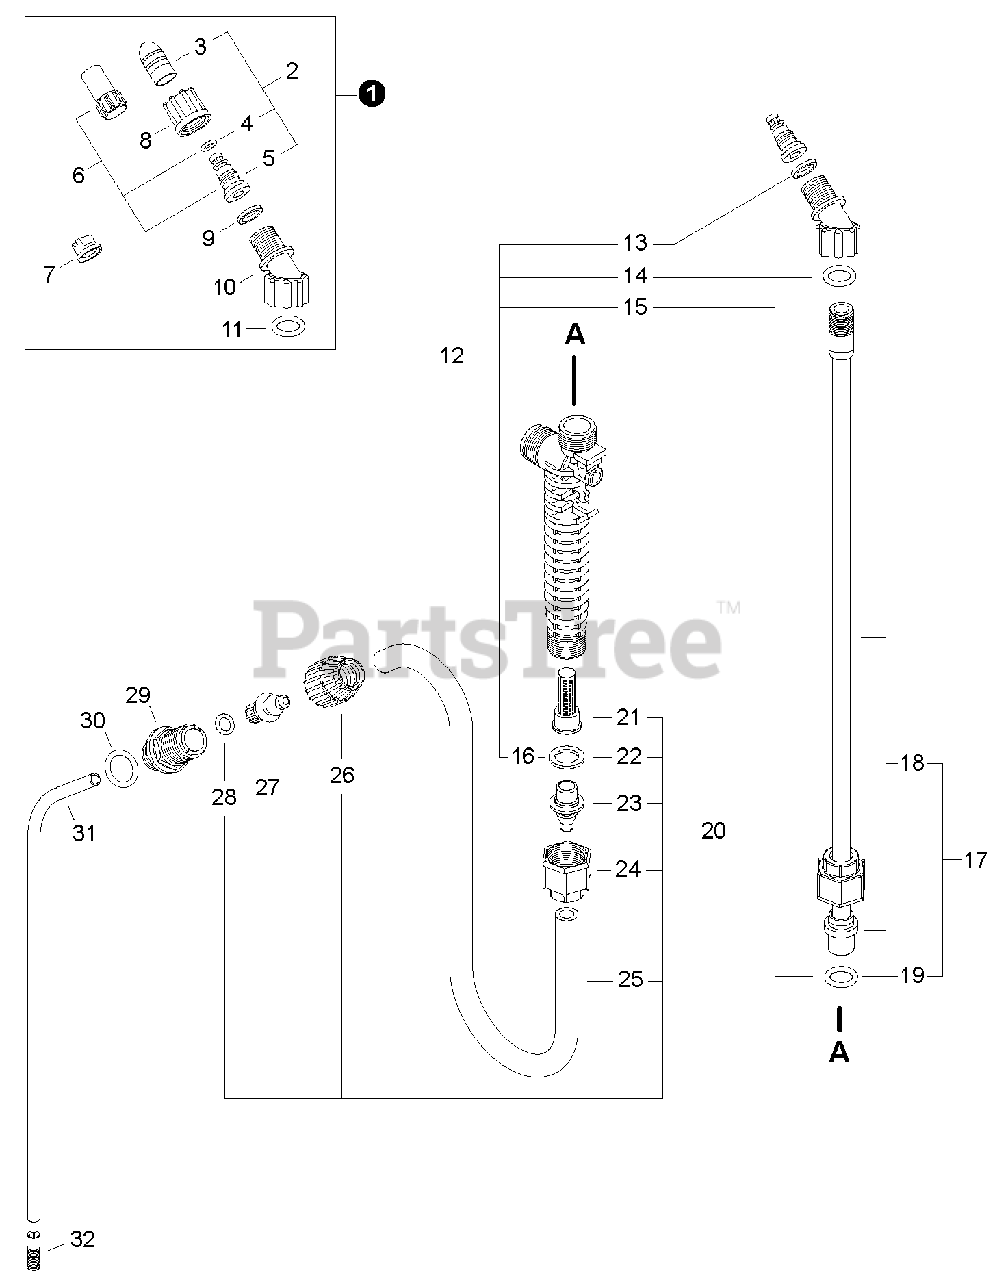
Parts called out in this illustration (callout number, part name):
1	NOZZLE KIT
2	NOZZLE KIT, BRASS
3	CAP, NOZZLE - BRASS
4	O-RING, NOZZLE
5	BODY, NOZZLE
6	NOZZLE KIT, PLASTIC
7	NOZZLE, FLAT FAN
8	NUT, NOZZLE
9	GASKET, NOZZLE
10	ELBOW, NOZZLE
11	O-RING, ELBOW
12	GASKET KIT, WAND
13	GASKET, NOZZLE
14	O-RING, ELBOW
16	GASKET, ADAPTER
17	WAND ASSY, PLASTIC
18	WAND, SPRAYER
20	HOSE KIT
21	FILTER, SPRAY GUN
22	GASKET, ADAPTER
23	ADAPTER, HOSE - BLACK
24	NUT, HOSE
26	NUT, TANK
27	ADAPTER, HOSE - WHITE
28	O-RING, ADAPTER
29	OUTLET, TANK 15/16
30	O-RING, TANK OUTLET
31	TUBE, OUTLET 16-1/4"
32	FILTER, OUTLET
